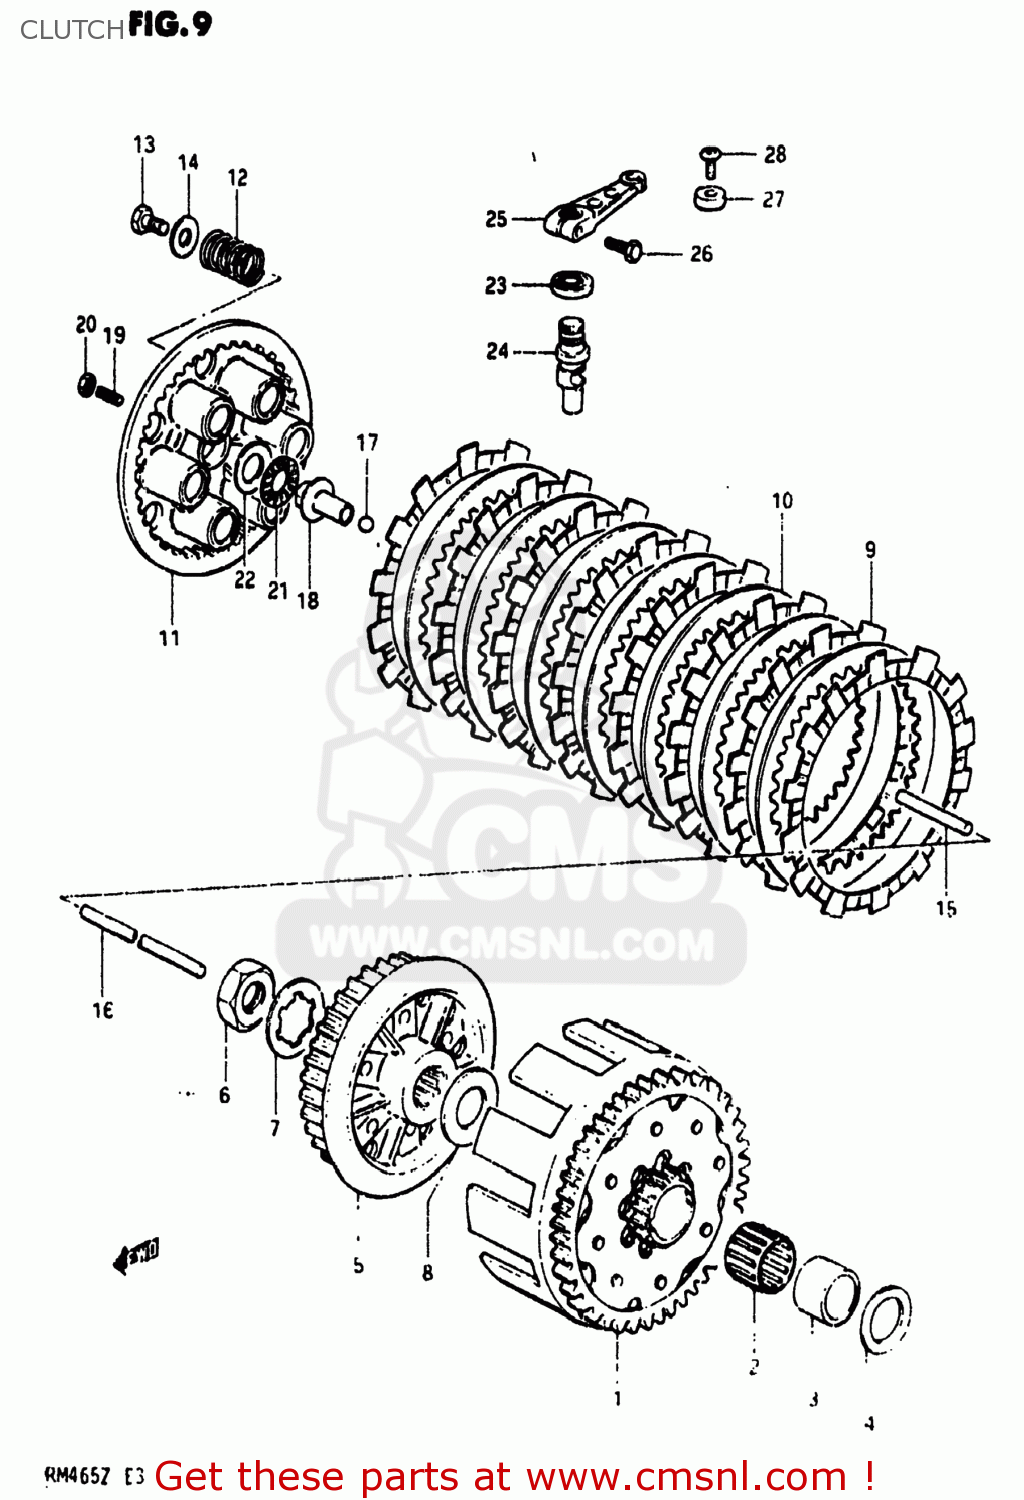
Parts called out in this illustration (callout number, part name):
1	GEAR ASSEMBLY,PRIMARY DRIVE
2	BEARING(28X33X27)
3	SPACER(22X28X27)
4	WASHER
5	HUB,CLUTCH SLEEVE
6	NUT
7	WASHER,LOCK
8	WASHER
9	PLATE,CLUTCH DRIVE (MCA)
10	PLATE,CLUTCH DRIVEN (NAS)
11	DISC,CLUTCH PRESSURE
12	SPRING
13	BOLT, UPPER
14	WASHER
15	ROD,CLUTCH PUSH NO.2
16	ROD,CLUTCH PUSH
17	BALL
18	PIECE,CLUTCH PUSH
19	SCREW
20	NUT 6MM
21	BEARING(15X28X2)
22	WASHER
23	SEAL,OIL(12X19X5)
24	SHAFT,CLUTCH RELEASE C
25	ARM,CLUTCH RELEASE
26	BOLT
27	GUIDE,CLUTCH CABLE
28	SCREW
